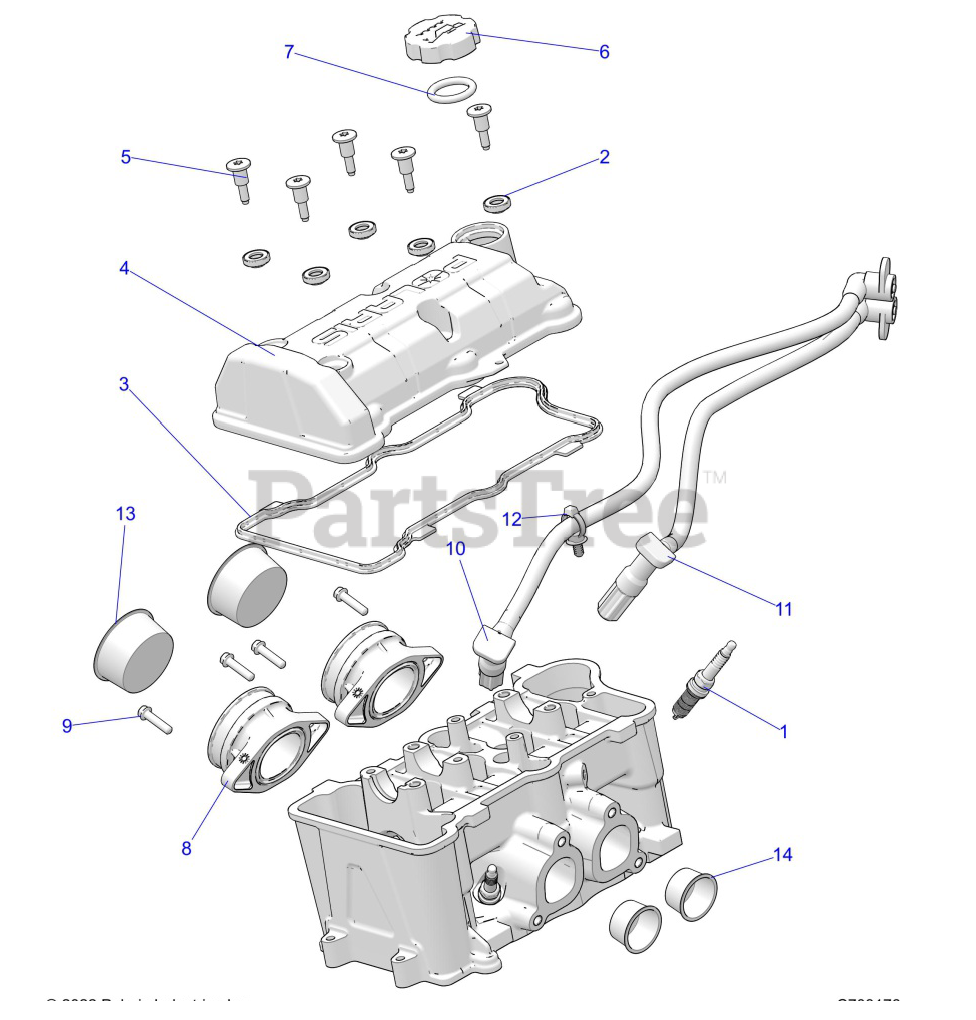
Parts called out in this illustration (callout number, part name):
1	SPARKPLUG-12MM
2	ISOLATOR-VALVE COVER
3	SEAL-VALVE COVER,2CYL,SOHC
4	COVER-VALVE,CAST,2CYL,SOHC
5	BOLT-SHLDR,M6X12X15
6	ASM-OIL FILL CAP
7	O-RING-FILL CAP
8	ADAPTER-MANIFOLD
9	SCR-HXFLG,M6X1.0X25,10.9
10	WIRE-SPARKPLUG,MAG
11	WIRE-SPARKPLUG,PTO
12	CLIP-ROUTING
